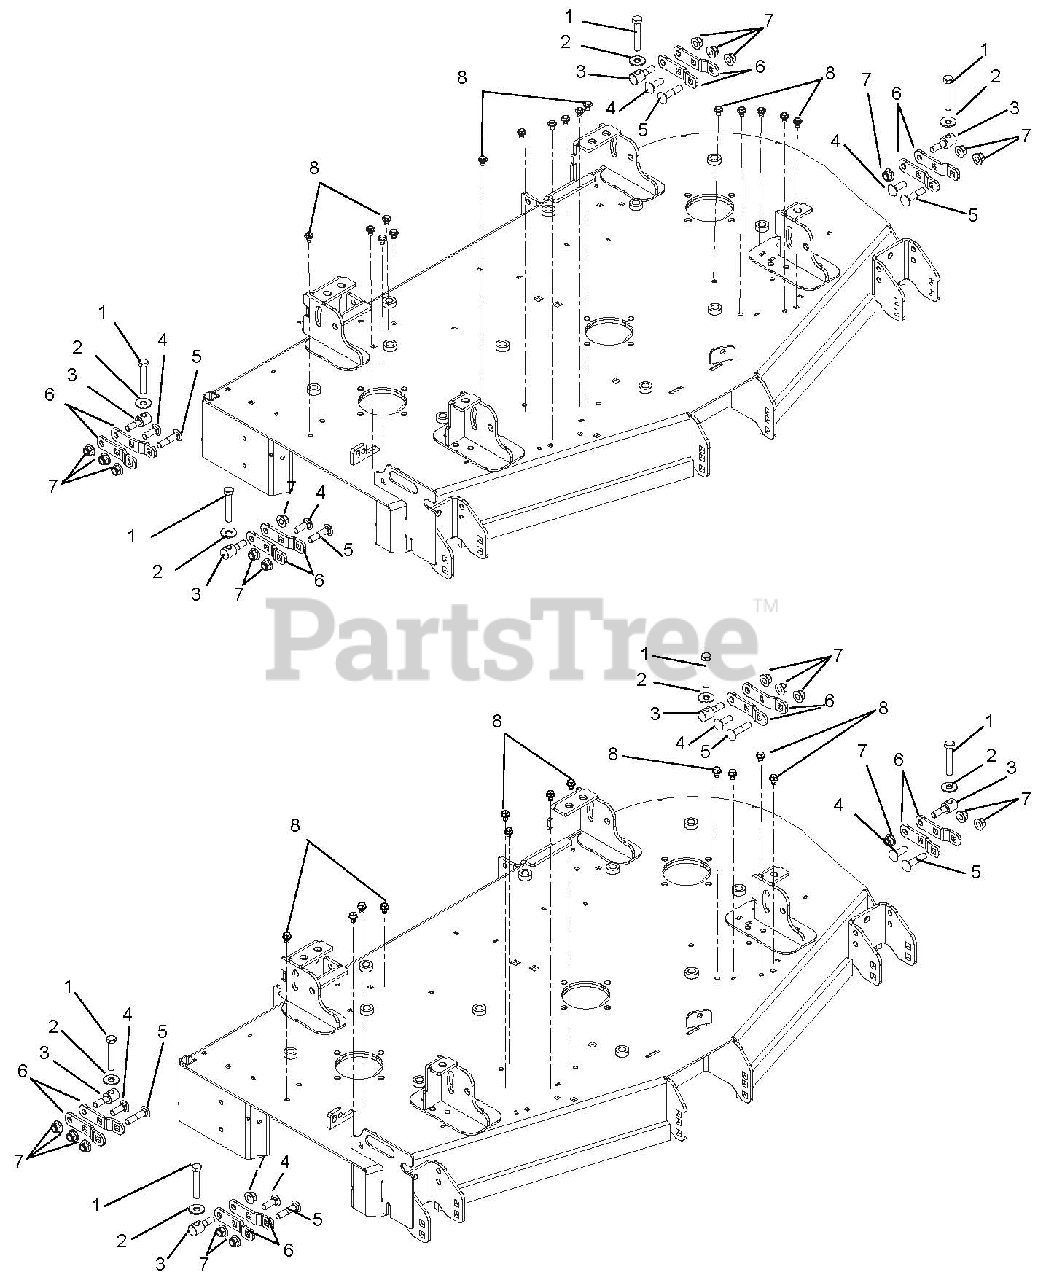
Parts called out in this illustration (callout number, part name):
1	Bolt, Hex .50-13 x 3.00 Grade 5 Full Thread
2	Washer, Flat Steel .563 x 1.38 x .109
3	Trunnion, .50-13
4	Bolt, Round Head Square Neck .50-13 x 1.50 Grade 5
5	Bolt, Round Head Square Neck .50-13 x 2.25 Grade 5
6	Deck Leveling Bracket – Black
7	Nut, Locking Nylon Flange .50-13
8	Screw, Tapping .38-16 x .50 Hex Washer Head
